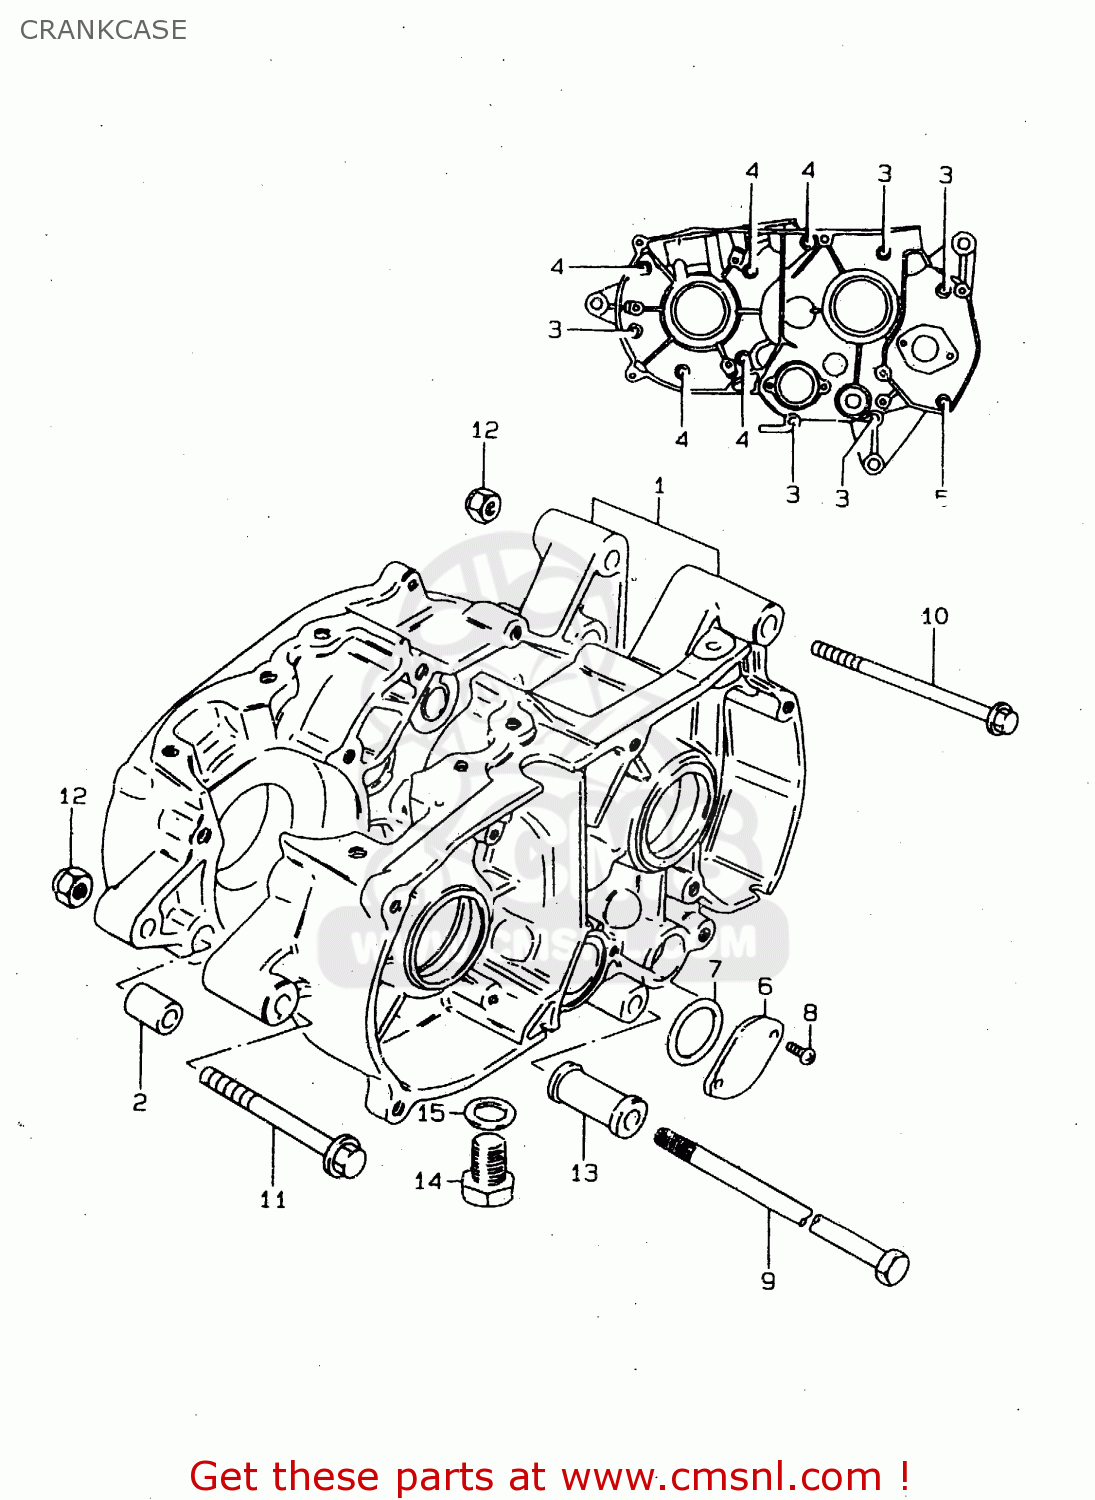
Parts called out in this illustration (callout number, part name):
1	CRANKCASE ASSEMBLY
2	PIN
3	SCREW
4	SCREW
5	SCREW
6	CAP,GEAR SHIFT CAM PIVOT
7	O-RING (D:2.4 ID:26.2)
8	SCREW
9	BOLT(8X230)
10	BOLT(8X100)
11	BOLT(8X70)
12	NUT
13	SPACER,ENGINE MOUNT(L:46)
14	BOLT
15	GASKET(10X14X3.6) (NAS)
